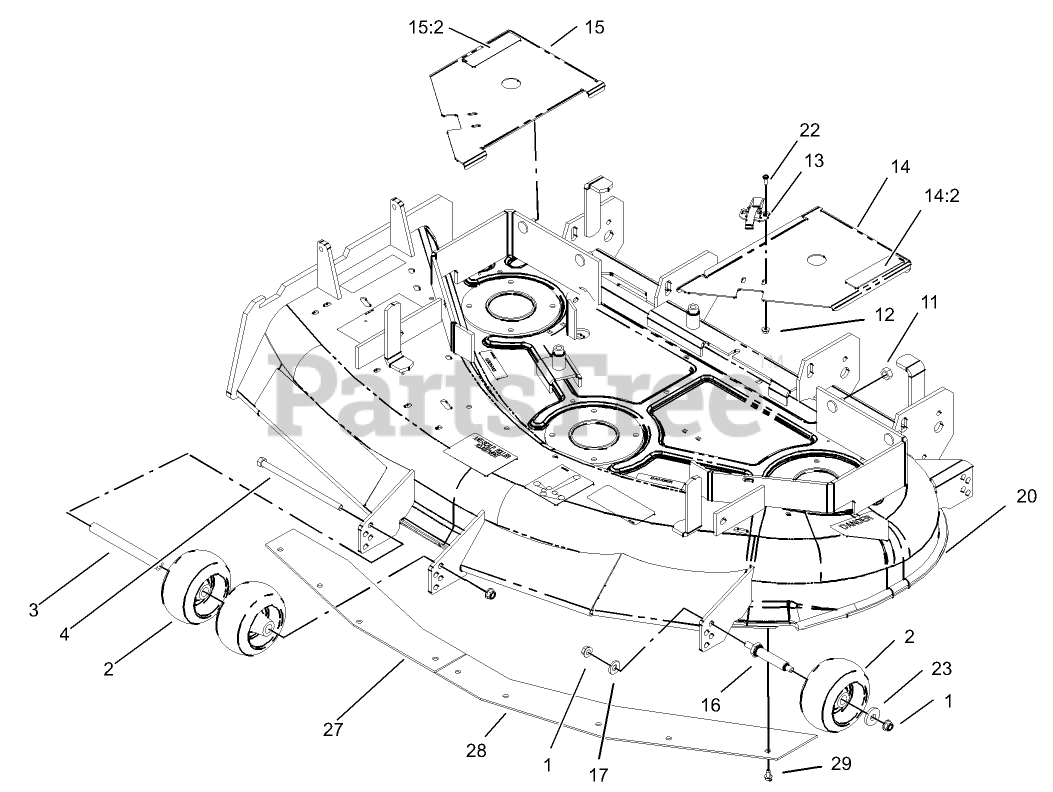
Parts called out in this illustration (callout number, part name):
1	NUT-HHF, WHIZ
2	WHEEL-GAGE
3	SPACER-WHEEL
4	SCREW-HH
11	NUT-LOCK, CONE
12	NUT-LOCK, FLANGE
13	CLAMP-SLOTTED
14	LH COVER ASM
14:2	DECAL-WARNING
15	RH COVER ASM
15:2	DECAL-WARNING
16	SPACER
17	WASHER-BELLEVILLE
20	DECK AND DEFLECTOR ASM
22	SCREW-HWH
23	WASHER
27	PLATE-BLOWOUT, RH
28	PLATE-BLOWOUT, LH
29	SCREW
